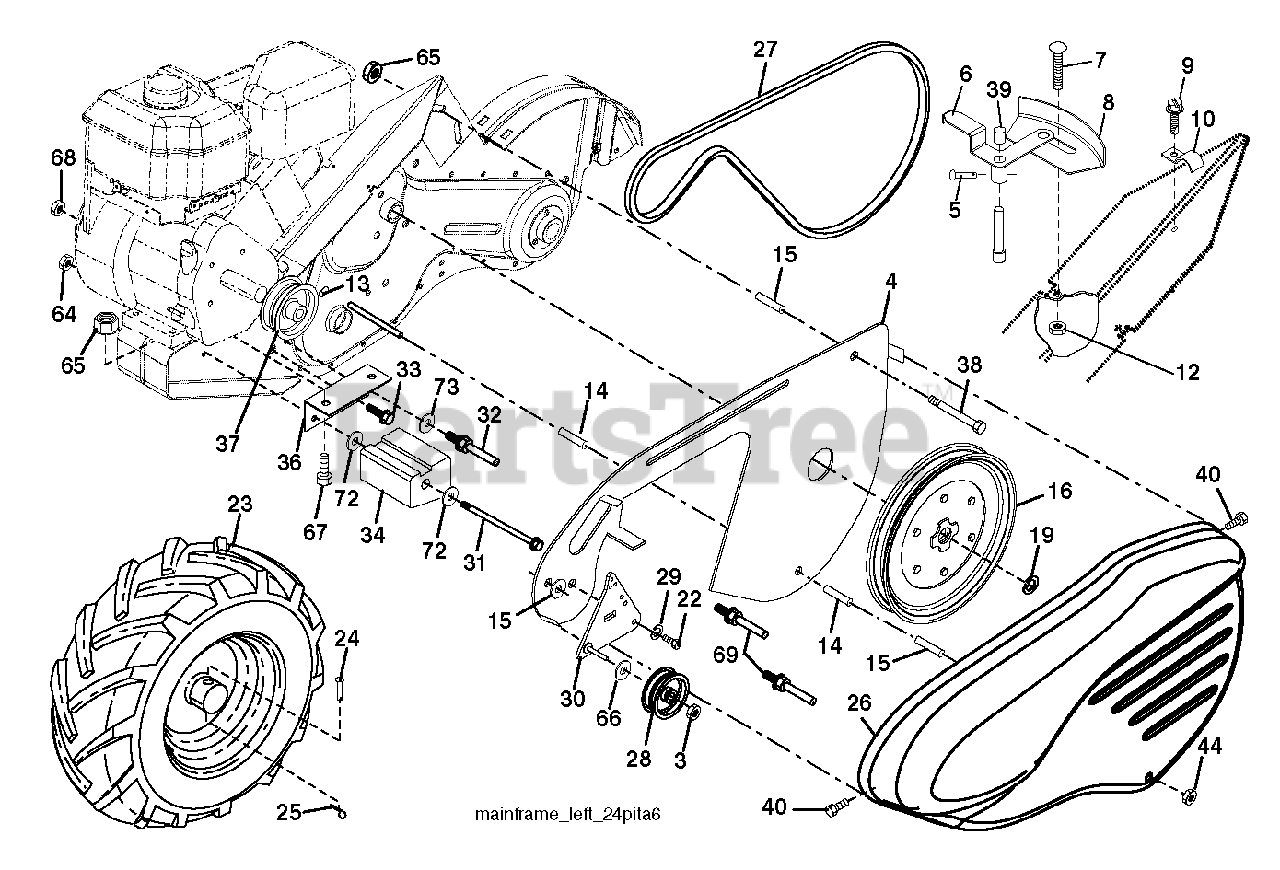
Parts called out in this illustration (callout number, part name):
3	LOCKNUT
5	PIN.SPIROL.FLARED
6	LEVER ASM CRT
9	TAPPING SCREW
10	CLIP.PLATED
12	NUT
13	SET SCREW **
14	SPACER-SPLIT.327 X .42
16	SHEAVE, TRANSMISSION
19	RETAINING RING LT
23	Wheel Assembly, CRT LH 13 X 5 X 6 Silver
24	RIVET
25	RETAINER M
27	V-BELT
28	PULLEY-IDLER TI
29	KLIP RING
30	Idler Assembly Bracket, Long
31	BOLT.FIN.HEX.3/8-16UNC X 11.5
32	SHIFT ARM CRT
33	BOLT
34	COUNTERWEIGHT.LH
37	ENGINE PULLEY
38	BOLT
39	CAP.PLUNGER.BLACK
40	SCREW.HEX.WSH.SLT.#10-24X.50
44	NUT.71038.31-18.HEX.NYLOCK
64	LOCKNUT
65	LOCKNUT-FLANGE 5/16-18
67	BOLT
69	KEEPER.BELT.ENGINE
73	WASHER
